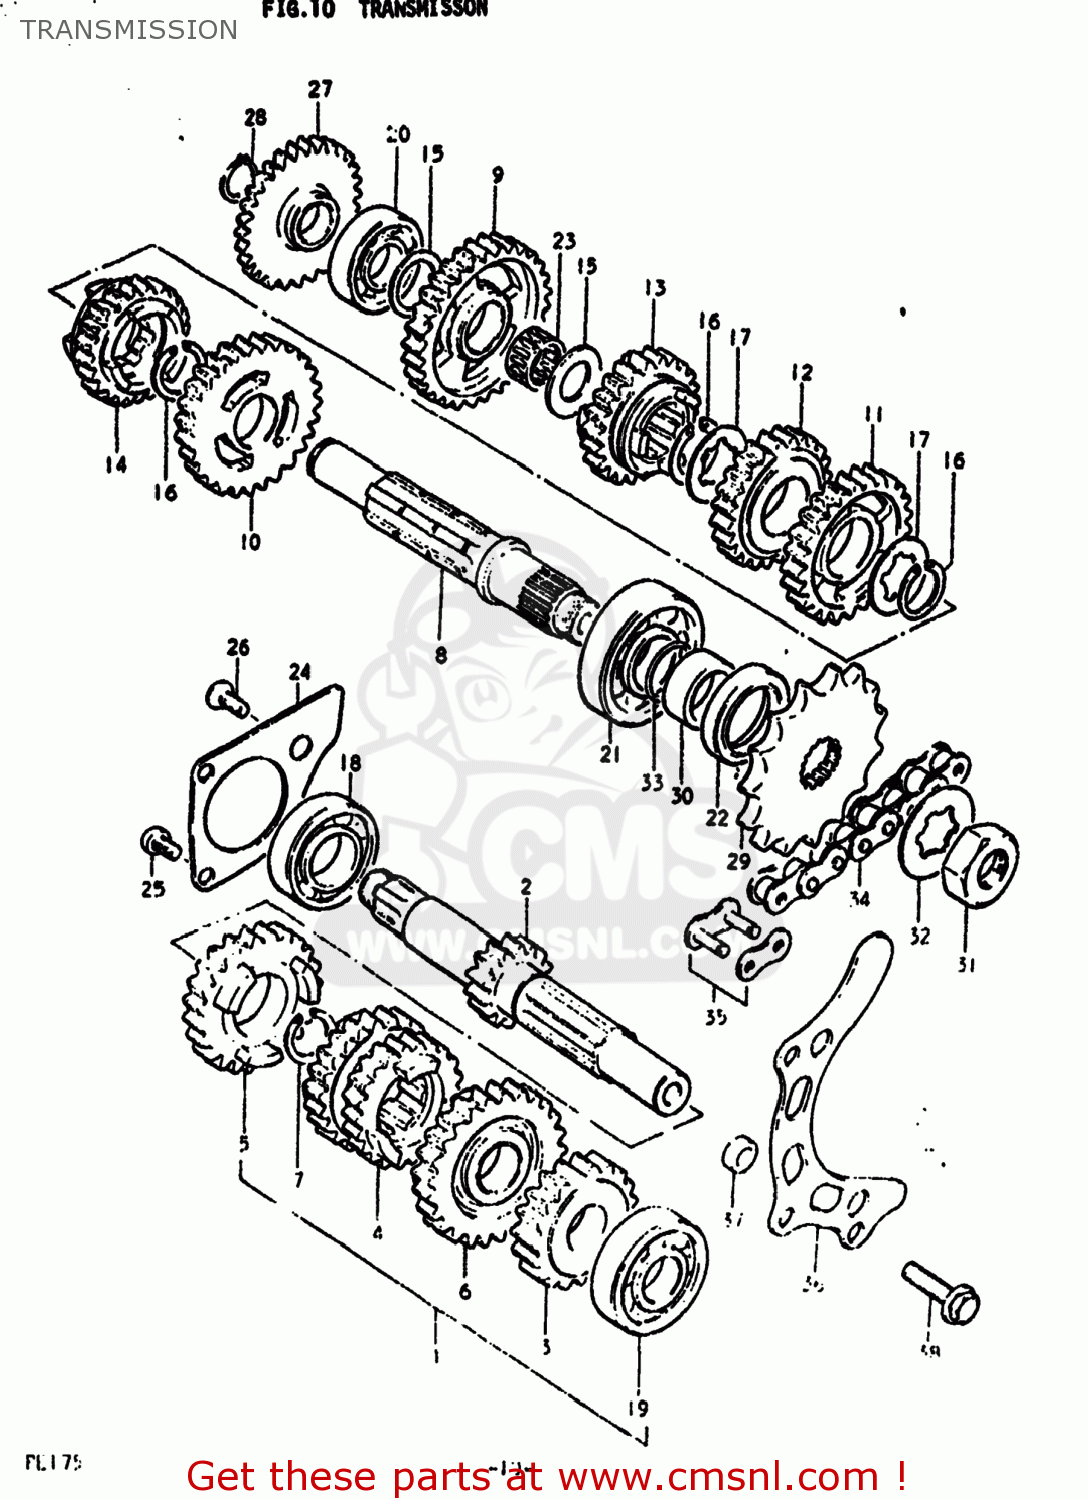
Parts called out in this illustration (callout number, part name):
1	SHAFT,COUNTER
2	SHAFT,COUNTER
3	GEAR,SECOND DRIVE
4	GEAR,THIRD DRIVE
5	GEAR,FIFTH DRIVE
6	GEAR,SIXTH DRIVE
7	CIRCLIP
8	SHAFT,DRIVE
9	GEAR,FIRST DRIVEN
10	GEAR,SECOND DRIVEN
11	GEAR,THIRD DRIVEN
12	GEAR,FOURTH DRIVEN
13	GEAR,FIFTH DRIVEN
14	GEAR,SIXTH DRIVEN
15	WASHER,THRUST
16	CIRCLIP
17	WASHER,LOCK
18	Bearing
19	BEARING
20	BEARING, RH
21	BEARING(20X47X14)
22	SEAL,OIL(25X40X7)
23	ROLLER BEARING (15X19X9
24	PLATE,COUNTERSHAFT BEARING
25	SCREW 6X12
26	SCREW
27	GEAR,KICK STARTER IDLE
28	CIRCLIP,15MM
29	SPROCKET,ENGINE
30	SPACER(20X25X12.5)
31	NUT
32	WASHER,LOCK
33	O RING(D:1,ID:19.5)
34	CHAIN ASSEMBLY,DRIVE
35	JOINT ASSEMBLY,CHAIN
36	PLATE,FRONT CHAIN GUIDE
37	SPACER(6.5X14X7.5)
38	BOLT
